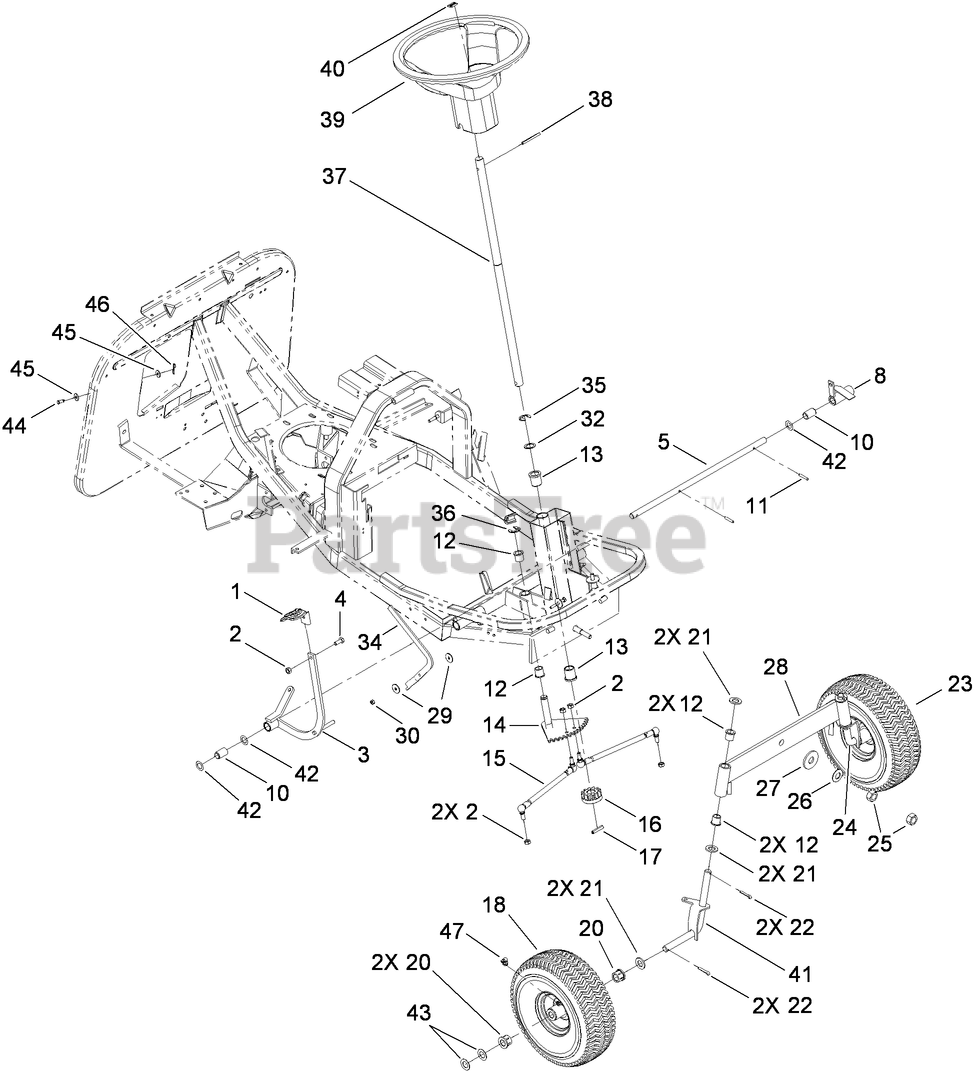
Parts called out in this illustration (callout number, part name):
1	Pedal-Brake
2	NUT-LOCK
3	LEVER-CLUTCH
4	SCREW-HH
8	Bushing
10	Bushing
11	Pin-Dowel
12	Bushing
13	Bushing
14	Rack-Steering
15	Rod-Tie
16	Gear-Steering
20	Bushing
21	WASHER-FLAT
22	PIN-COTTER
24	AXLE-WHEEL, LH
25	NUT-HEX
27	Washer-Flat
28	Axle-Front
29	Washer-Flat
30	NUT-LOCK
32	Spacer
35	RING-RETAINING, EXT
36	RING-RETAINING, EXT
37	Shaft-Steering
38	Pin-Roll
39	WHEEL-STEERING
40	DECAL
41	AXLE-WHEEL, RH
42	Spacer
43	Washer
45	Washer-Flat
46	Pin-Hair
47	ZERK-GREASE, 90 DEG
